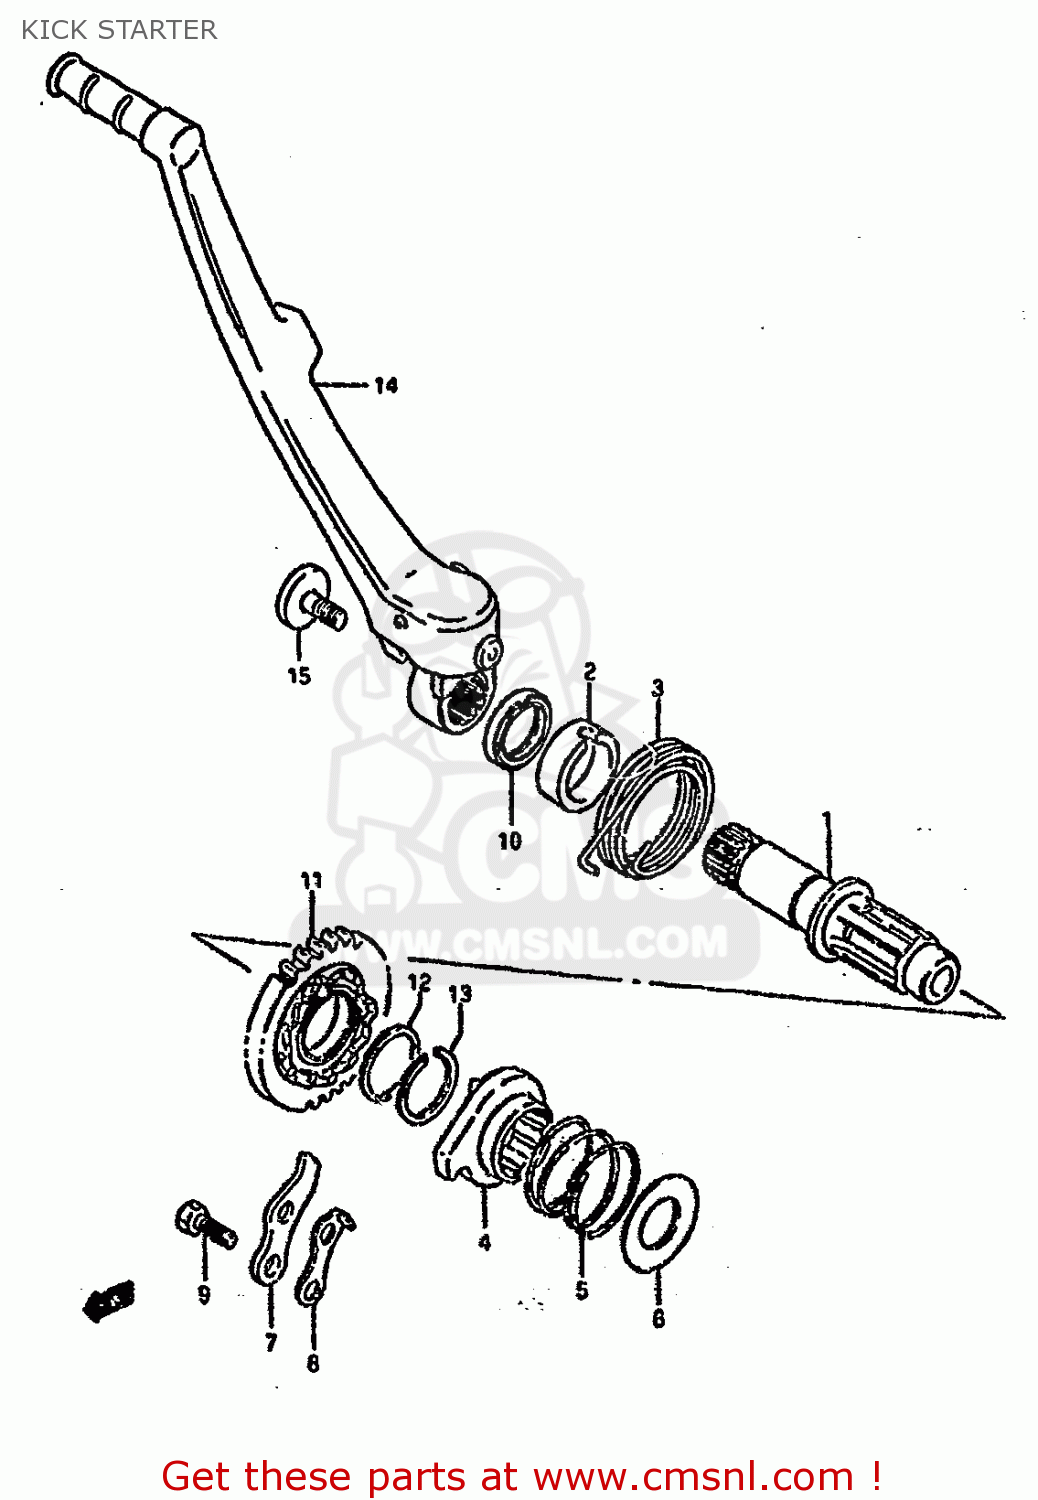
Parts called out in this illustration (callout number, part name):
1	SHAFT,KICK STARTER
2	GUIDE,KICK STARTER SHAFT
3	SPRING
4	STARTER,KICK
5	SPRING
6	WASHER
7	GUIDE,KICK STARTER
8	STOPPER,KICK STARTER
9	BOLT
10	SEAL,OIL(20X27X5)
11	GEAR COMP,KICK STARTER
12	SHIM
13	CIRCLIP
14	LEVER ASSEMBLY,KICK STARTER
15	BOLT (8X14)
